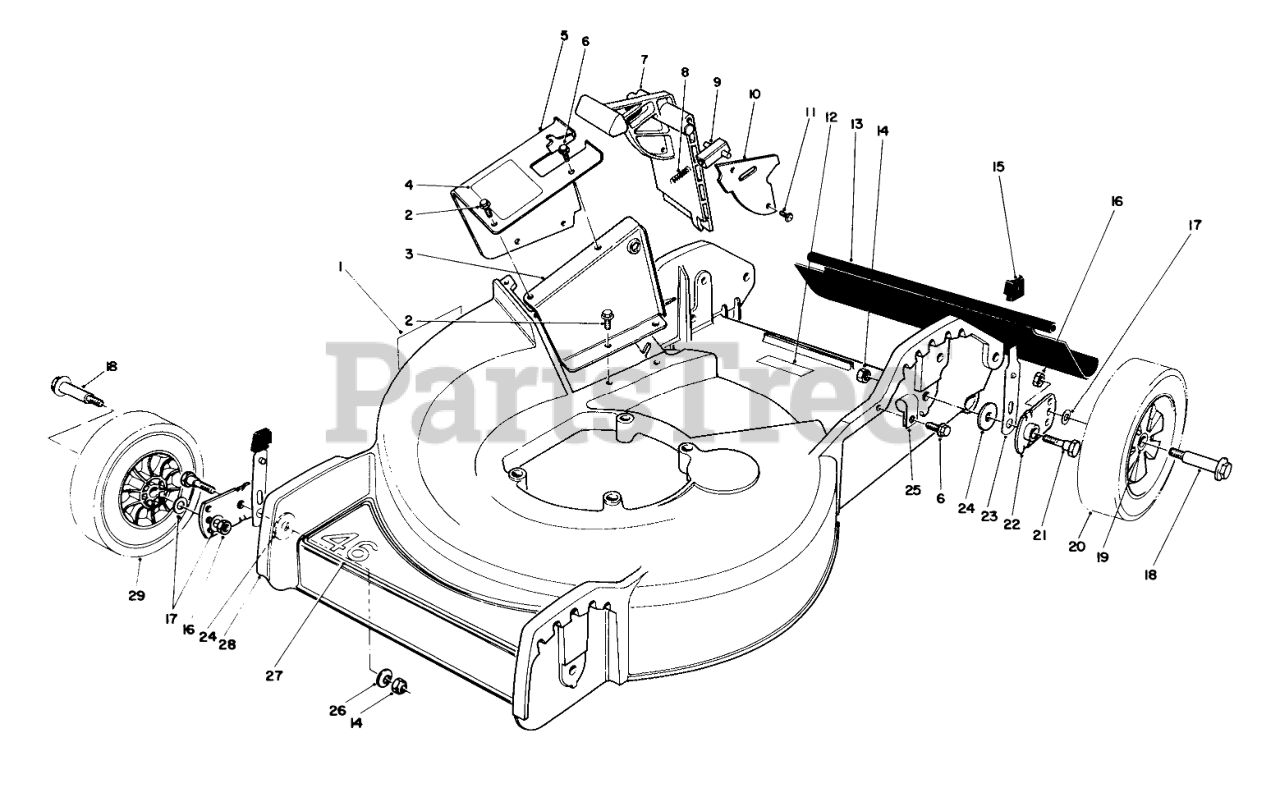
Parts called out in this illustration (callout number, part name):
1	Decal Danger
2	SCREW
3	Tunnel-Inner
4	DECAL - DANGER
5	Tunnel-Outer (Incl. Ref. #4)
6	SCREW
7	Door Mulching
8	SPRING-COMPRESSION, LATCH
9	Door Latch
10	Cover Door
12	Decal
13	SHIELD - TRAILING
14	NUT-LOCK, NI
15	KNOB-ARM
16	Nut
17	WASHER
18	BOLT-WHEEL
19	BUSHING
20	Wheel & Tire Assembly (Incl. Ref. #18)
21	PIVOT SCREW
22	PIVOT ARM ASSY
23	SPRING ARM ASM
24	PIVOT WASHER
25	CLAMP-R
26	WASHER-BELLEVILLE
27	DECAL - DECK
28	HSG & CARTON
29	Wheel & Tire Assembly (Incl. Ref. #18)
